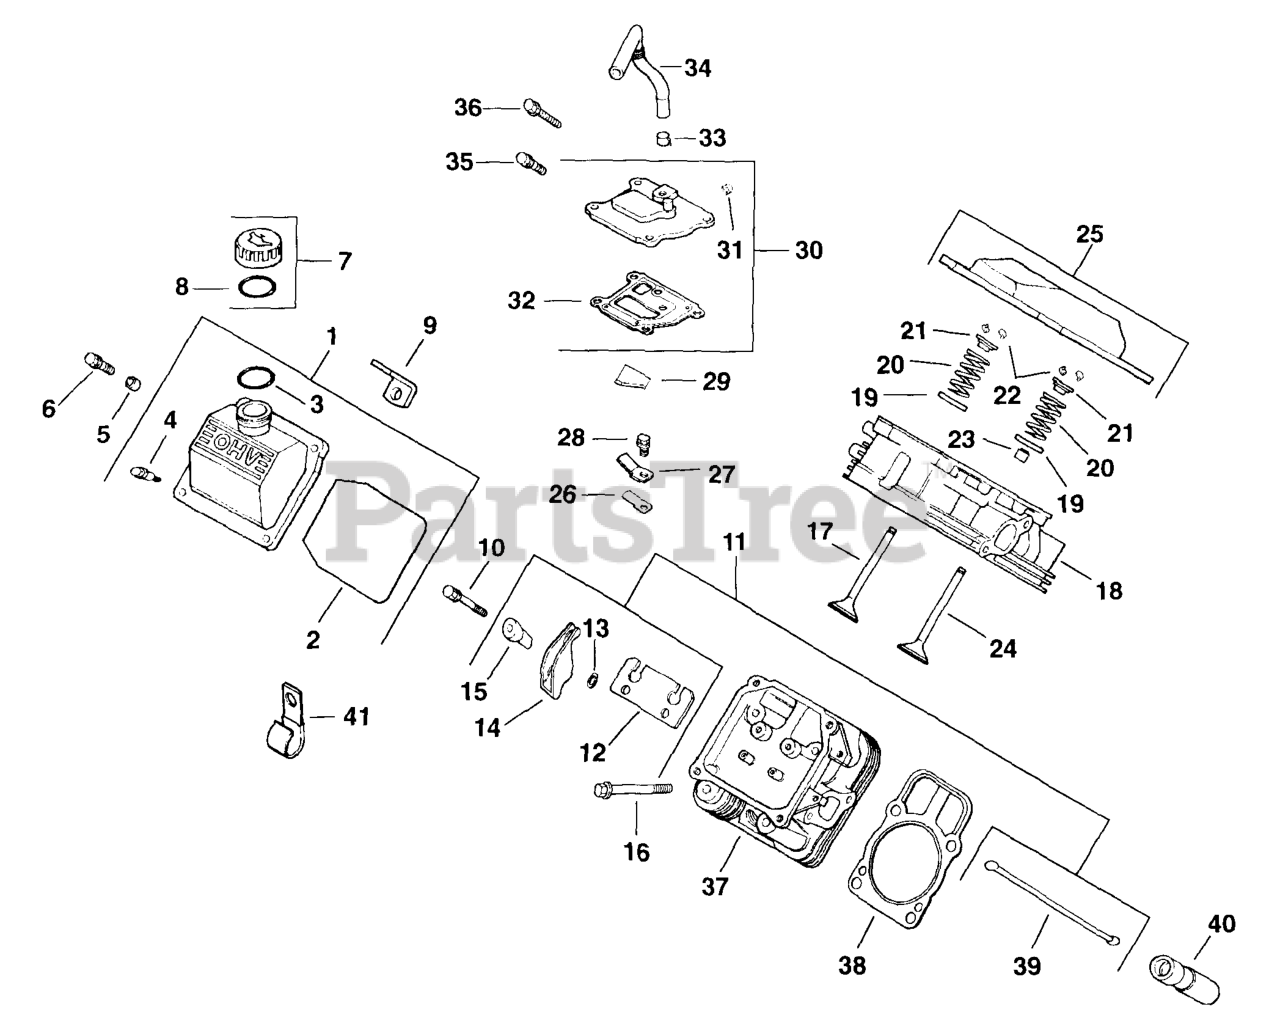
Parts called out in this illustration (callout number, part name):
1	Kit, Valve Cover - Oil Fill
4	Screw, Hex. Cap - Shoulder M6x1.0x23
7	Kit, Oil Fill Cap
9	Strap, Lifting
10	Screw, Hex. Flange M6x1.0x34
11	Kit, Valve Train
12	Plate, Guide
13	Washer, Plain 6 Mm
14	Arm, Rocker
15	Pivot, Rocker Arm
16	Screw, Hex. Flange M10x1.5x91
17	Valve, Exhaust (Std.)
17	Valve, Exhaust (.25 O.S.)
18	Head Assembly, #1 Cylinder
19	Retainer, Spring
20	Spring, Valve
21	Cap, Valve Spring
22	Kit, Retainer
23	Seal, Valve Stem
24	Valve, Intake (Std.)
24	Valve, Intake (.25 O.S.)
25	Kit, Valve Cover - Plain
26	Reed, Breather
27	Retainer, Breather Reed
28	Screw, Hex. Flange M5x0.8x10
29	Filter, Breather
30	Kit, Breather W/Plug
31	Plug, Allen Hd. 1/8"
32	Gasket, Breather
33	Clamp, Hose
34	Hose, Breather
35	Screw, Hex. Flange M6x1.0x20
37	Head Assembly, #2 Cylinder
38	Gasket, Cylinder Head
39	Rod, Push
40	Lifter, Valve
